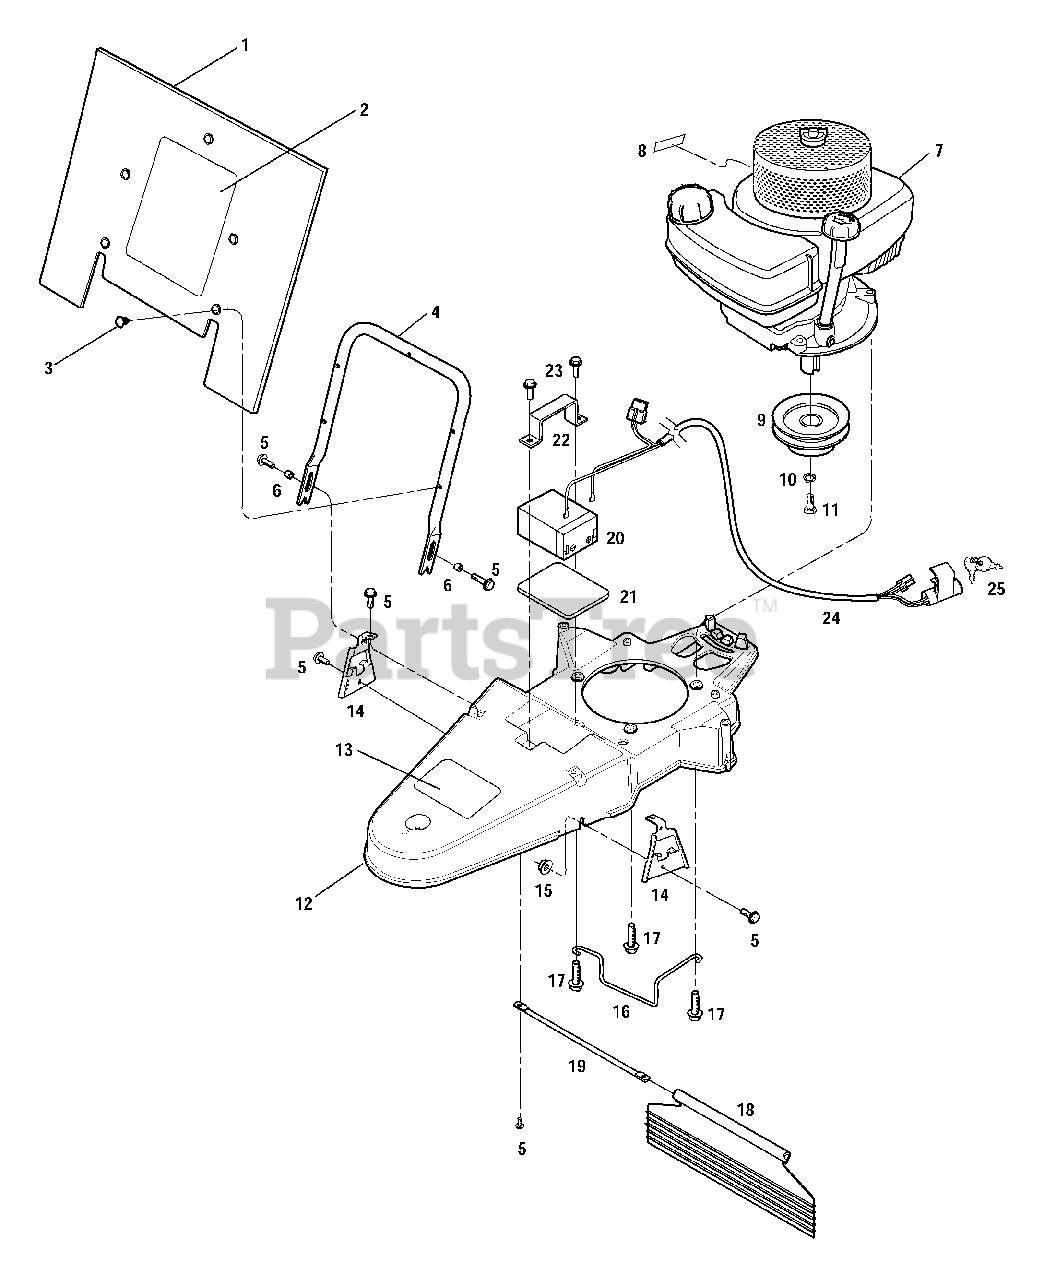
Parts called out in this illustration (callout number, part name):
1	Debris Guard
2	Decal-Logo
3	Push-in Fastener
4	Debris Guard Support
5	Hex Flange Screw, 1/4-20 x 3/4
6	Spacer
7	Engine
8	Decal-Hot Surface Warning
9	Engine Pulley
10	Spring Lock Washer
11	Hex Hd. Screw, 3/8-24 x 1, Grade 5
12	Deck
13	Decal-Warning
14	Hood Bracket
15	Flange Lock Nut, 1/4-20
16	Belt Guide
17	Hex Hd. Screw, 3/8-16 x 1-1/2
18	Deflector Flap
20	Battery
21	Battery Pad
22	Battery Clamp
23	Hex Flange Screw, 5/16-18 x 1
24	Wire Harness
25	Ignition Key
